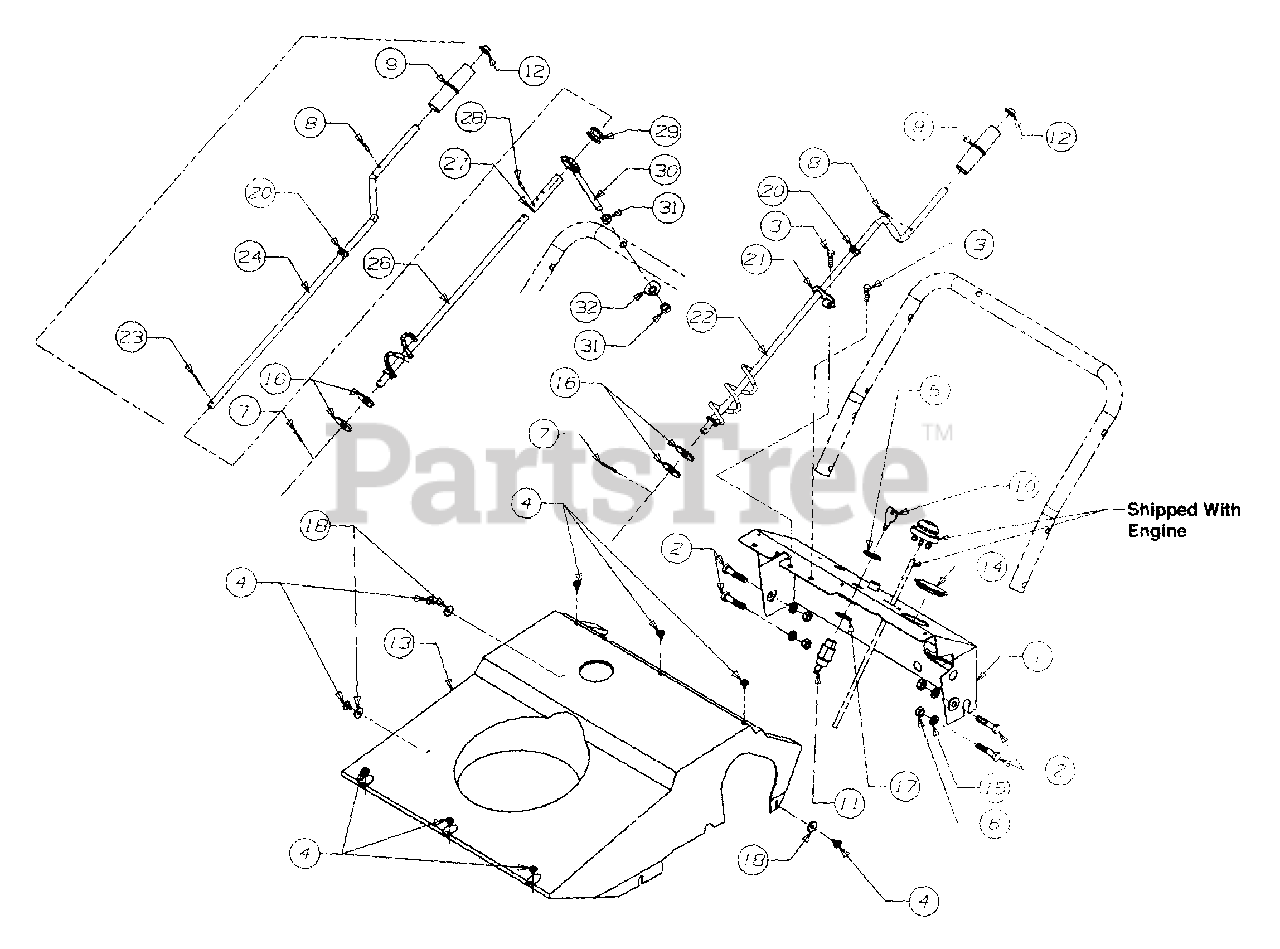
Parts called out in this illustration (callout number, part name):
3	Screw - Hex Tap
4	Screw - Hex Tap
5	Nut Hex
6	Nut - Hex
7	Pin - Cotter
8	Pin Roll
9	Knob - Chute Crank
10	Key - Ignition
11	Switch - Key
12	Nut Push
13	Shroud
14	Plug
15	Washer Lock
16	Washer - Flat
17	Washer Internal Lock
18	Washer Flat
20	Bushing
21	Bracket Chute Crank
22	Crank Ass'y. Chute
23	Cotter Pin
28	Pin - Roll
29	Grommet - Rubber
30	Eyebolt - Chute Crank
31	Nut - Hex
32	Washer - Saddle
